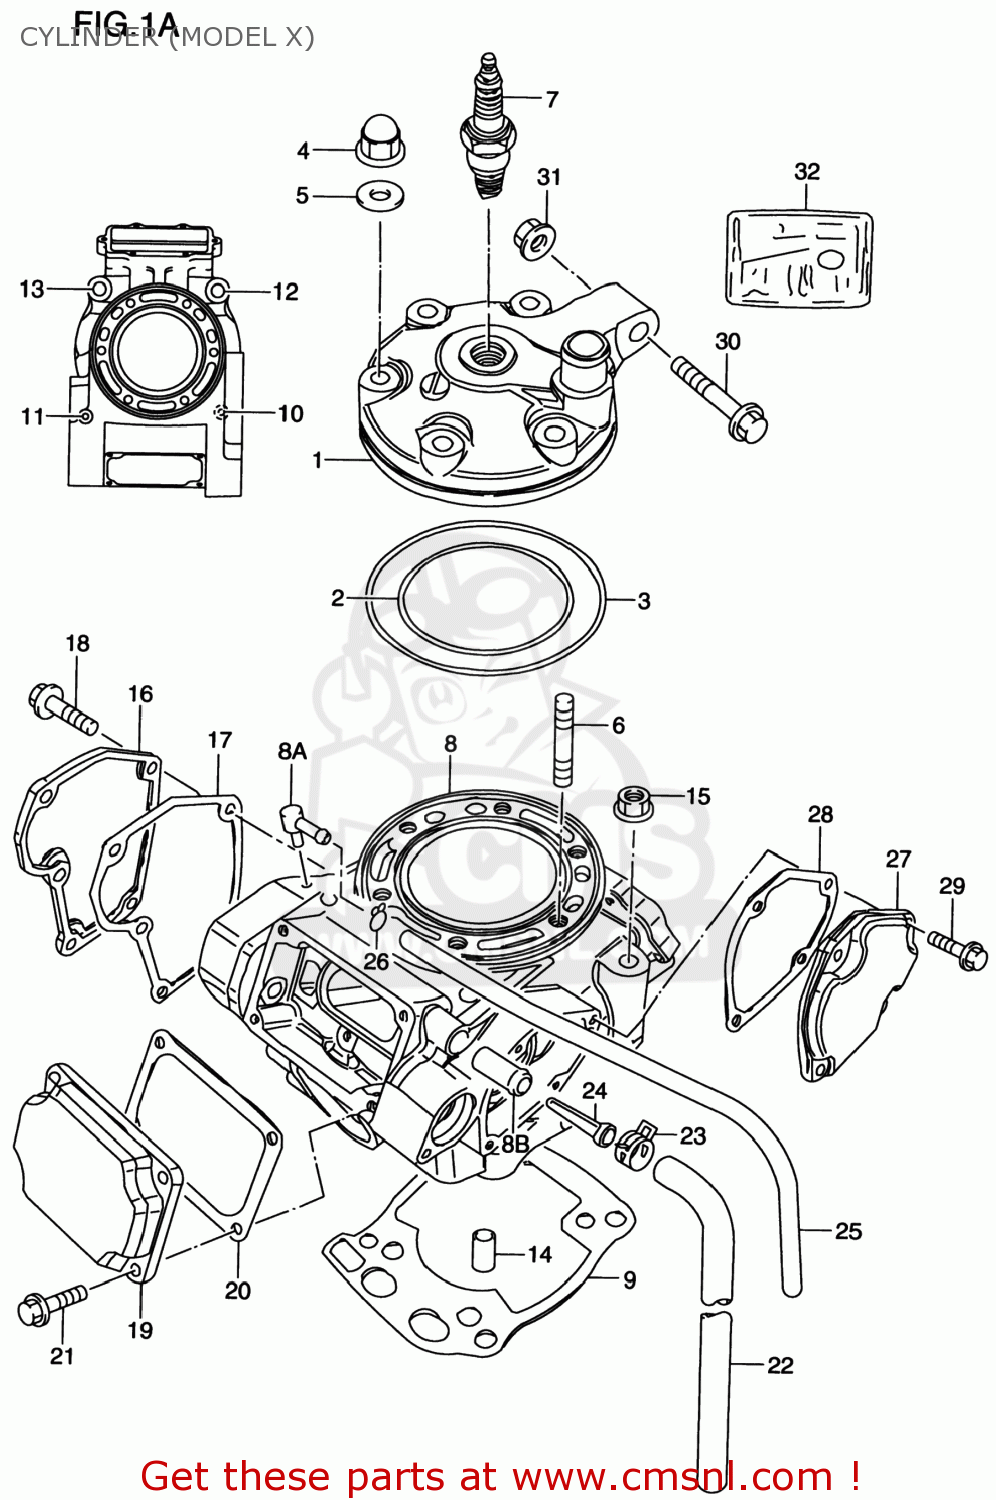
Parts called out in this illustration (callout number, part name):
1	HEAD,CYLINDER
2	O RING,CYLINDER HEAD NO.1
3	O RING,CYLINDER HEAD NO.2
4	NUT
5	GASKET(8.5X17X2.3) (NAS)
6	BOLT,STUD
7	PLUG,SPARK(R6918B-7)
8	CYLINDER SET
8A	UNION,BREATHER HOSE
8B	UNION
9	GASKET,CYLINDER (NAS)
10	STUD 10X30
11	STUD BOLT (L:40)
12	STUD BOLT (L:70)
13	STUD BOLT
14	PIN(13X10.4X20)
15	NUT
16	COVER,CYLINDER NO.1
17	GASKET,CYLINDER COVER NO.1 (NAS)
18	BOLT
19	COVER,CYLINDER NO.2
20	GASKET,CYLINDER COVER NO.2
21	BOLT
22	HOSE
23	CLIP
24	FILTER,EXH VALVE BREATHER HOSE
25	HOSE(5X8.2X600)
26	CLIP
27	COVER,CYLINDER NO.3
28	GASKET,CYLINDER COVER (NAS)
29	BOLT
30	BOLT(10X48)
31	NUT
32	GASKET SET (NAS)
